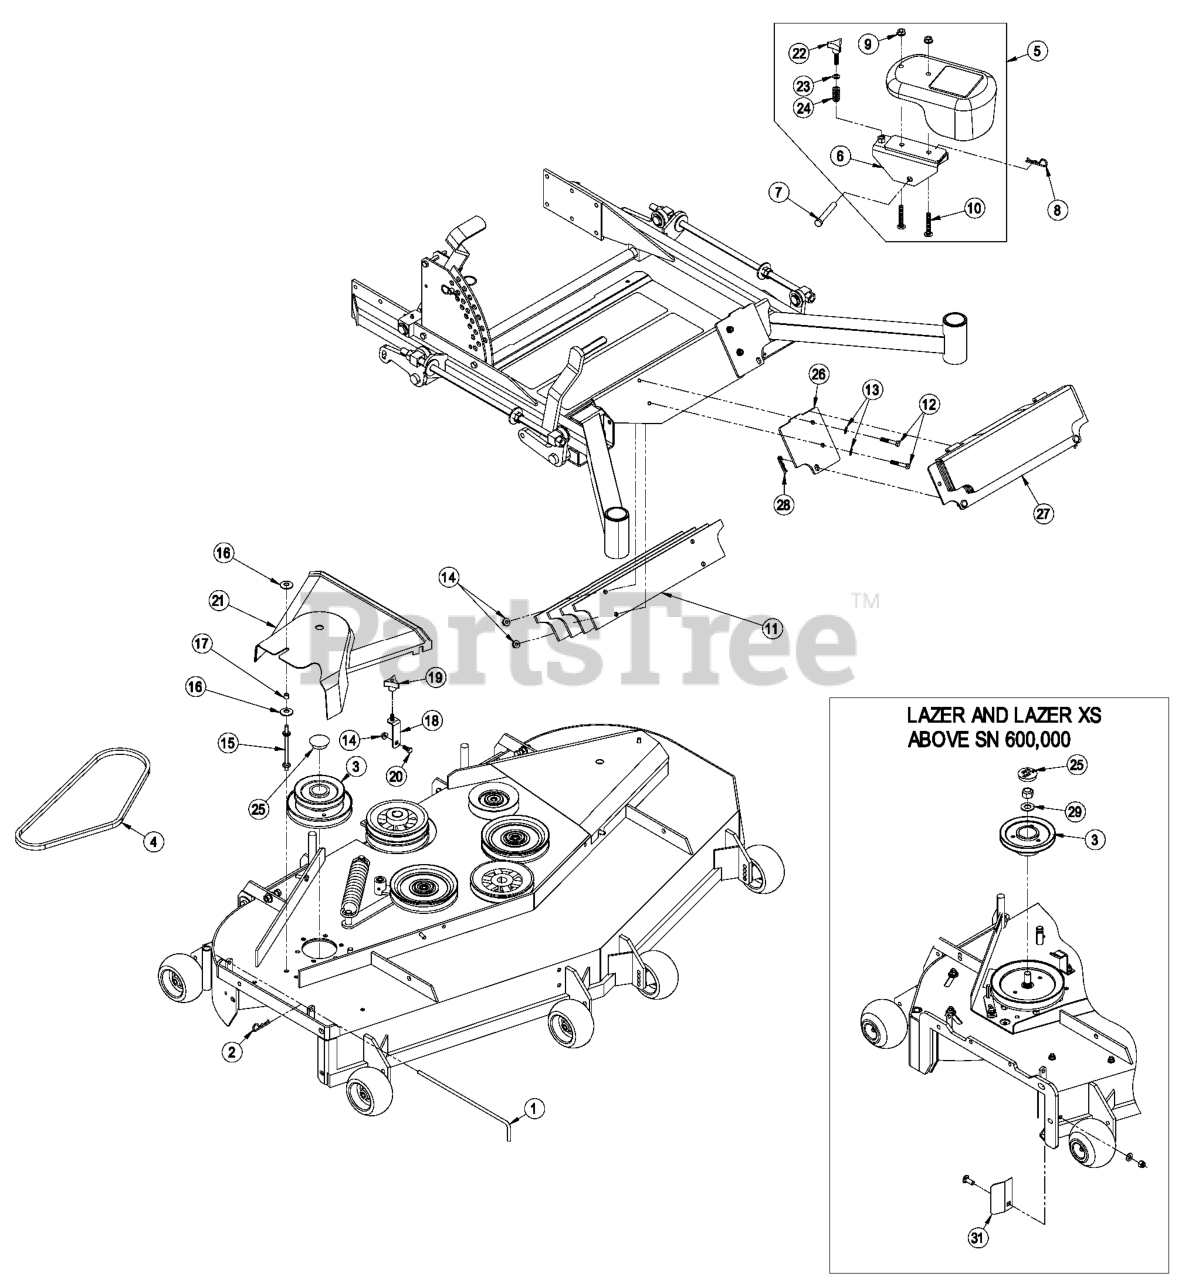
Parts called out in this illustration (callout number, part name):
1	PIN,CHUTE PIVOT
2	PIN-COTTER
3	JACKSHAFT, LZUV60
4	BELT, BLOWER 52"DECK
5	ASM, WEIGHT 1.5" 70 POUND
6	WLD, BRACKET 2.0 ARM
7	PIN-CLEVIS
8	PIN-COTTER
9	NUT-HHF, WHIZ
10	BOLT-SQH
11	PLATE, WEIGHT
12	SCREW-HH
13	WASHER-PLAIN
15	STUD,BELT SHIELD 4 INCH
16	WASHER-SPRING
18	WLD, BELT COVER SUPPORT
19	KNOB-3 PRONG
20	SCREW-HH
21	COVER, BELT LZ52
23	WASHER-FLAT
25	PLUG, BLACK NYLON 1.75
26	PLATE, WEIGHT MOUNTING
27	ASM, WEIGHT PLATE WITH DE
28	PIN-HAIR
29	WASHER-FLAT
31	DEFLECTOR,LZ UV
